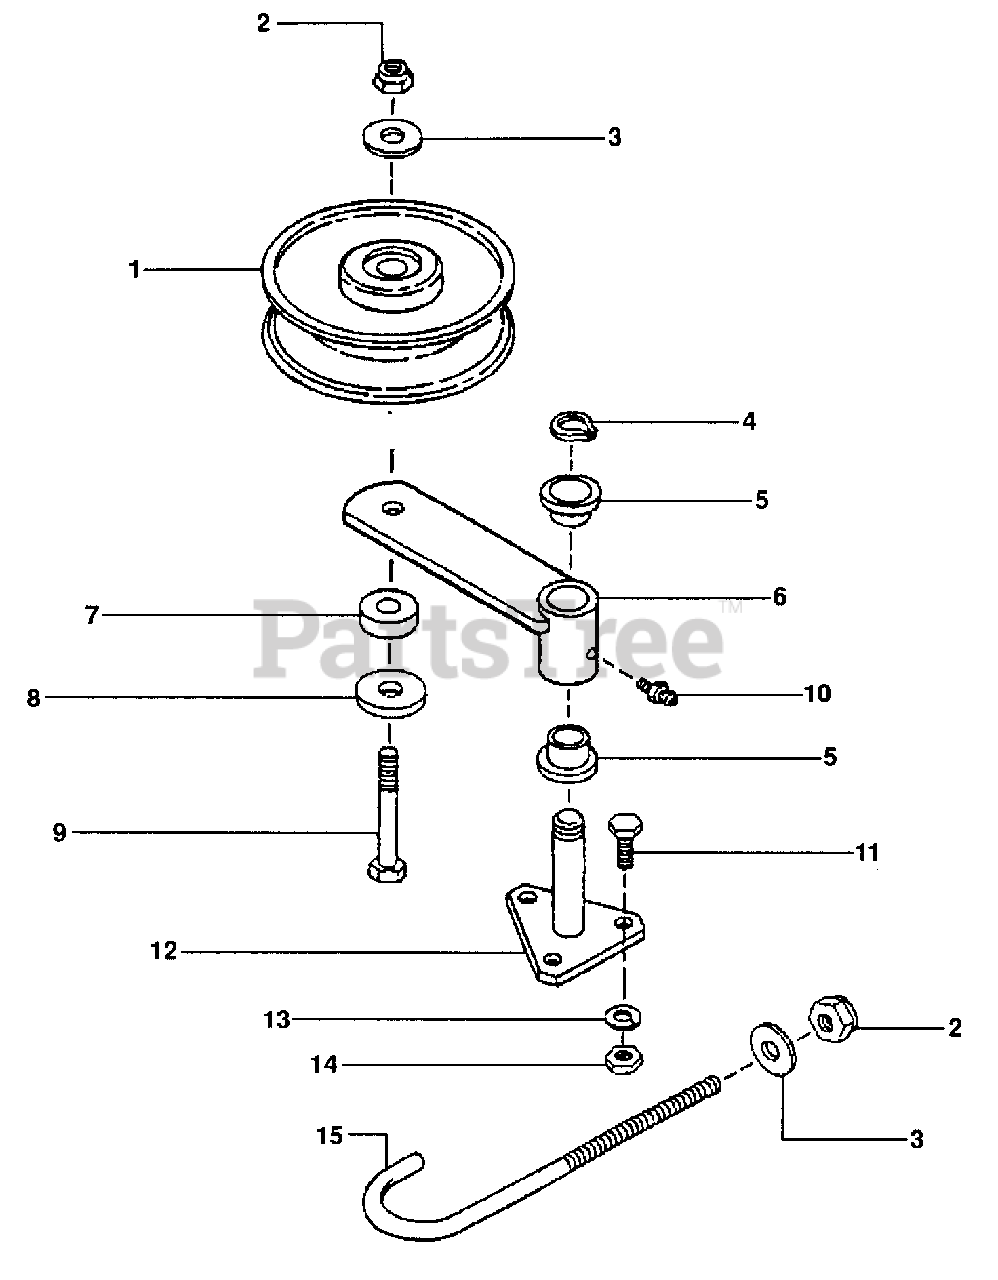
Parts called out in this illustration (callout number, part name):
1	PULLEY, Idler, V-Groove (5.00 O.D.)
2	NUT, 3/8-16 Hex Nyloc
3	WASHER, .44" I.D. x 1" O.D.
4	RING, 1" Retaining
5	BUSHING
6	IDLER ARM (Weldment), 48" Blade/Blade Deck
7	BUSHING, .38" 1.D. x 1" 0. D. x .41 0"
8	WASHER, 13/32" Flat
9	BOLT, 3/8-16 x 2 1/2" Hex Head Cap, Grade 8
10	FITTING, Lube
11	BOLT, 3/8-16 x 1" Hex Head Cap
12	PIVOT, Idler Arm
13	WASHER, 3/8" Split Lock
14	NUT, 3/8-16 Hex, Grade 5
15	HOOK, "J"
